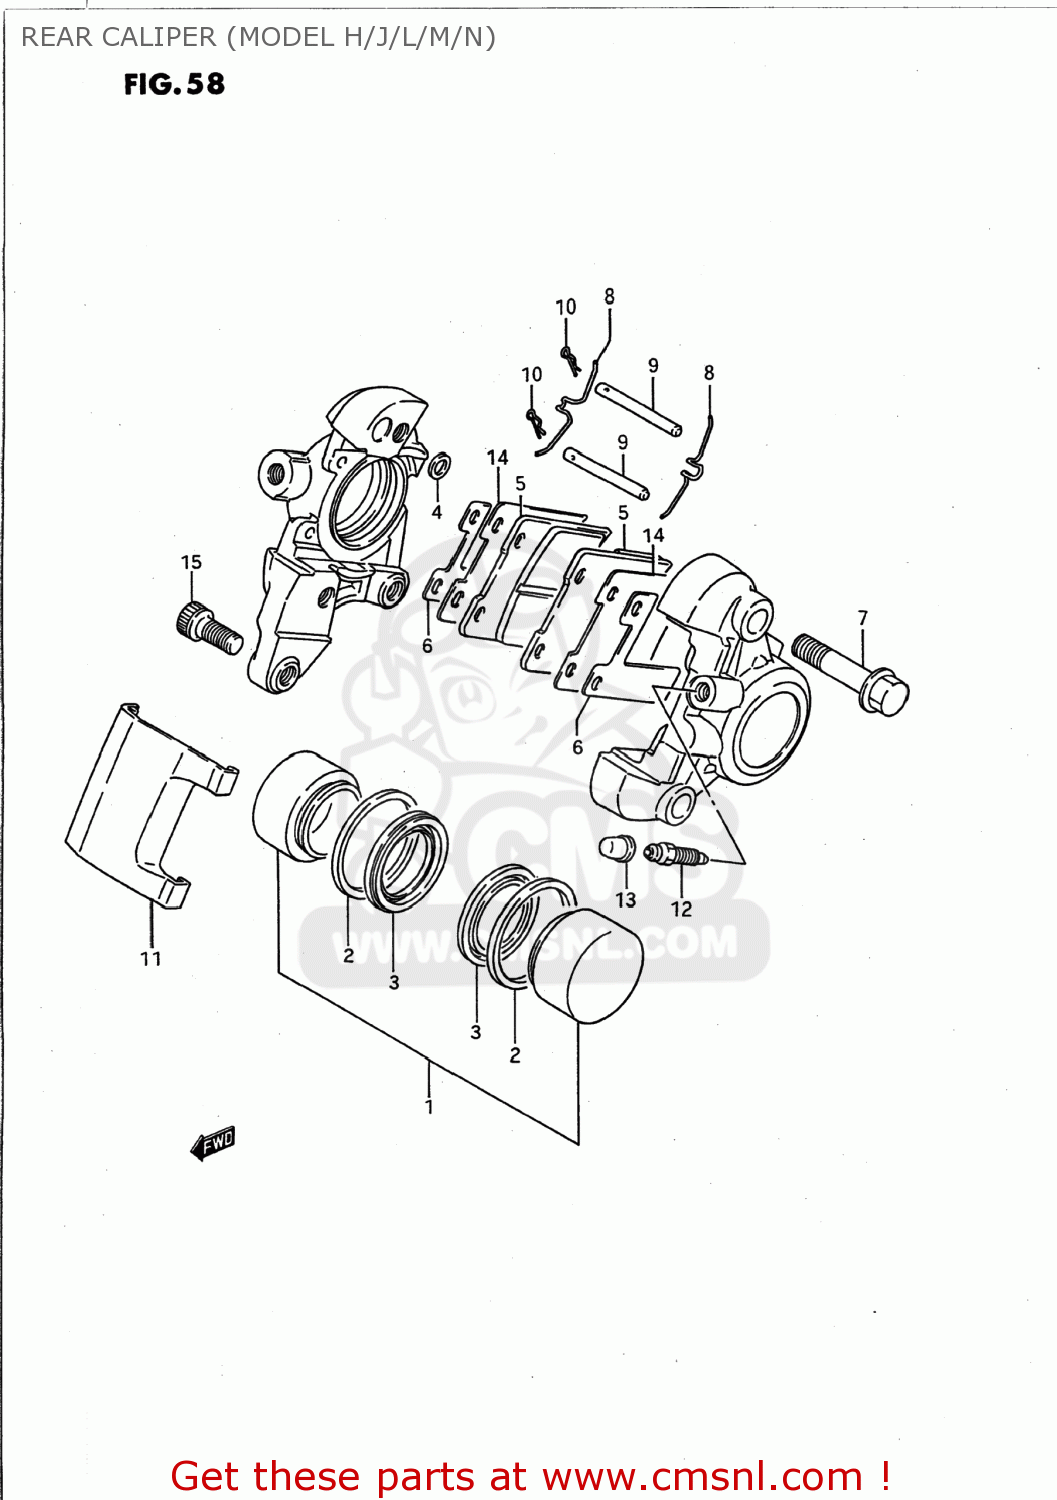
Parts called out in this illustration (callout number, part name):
1	PISTON SET
2	SEAL,FR CALIPE
3	BOOT,PISTON
4	SEAL,JOINT
5	PAD,BRAKE
6	SHIM
7	BOLT,HOUSING
8	SPRING
9	PIN,PAD
10	CLIP,PAD PIN
11	COVER
12	BLEEDER
13	CAP,BREATHER
14	SHIM,PAD
15	BOLT
